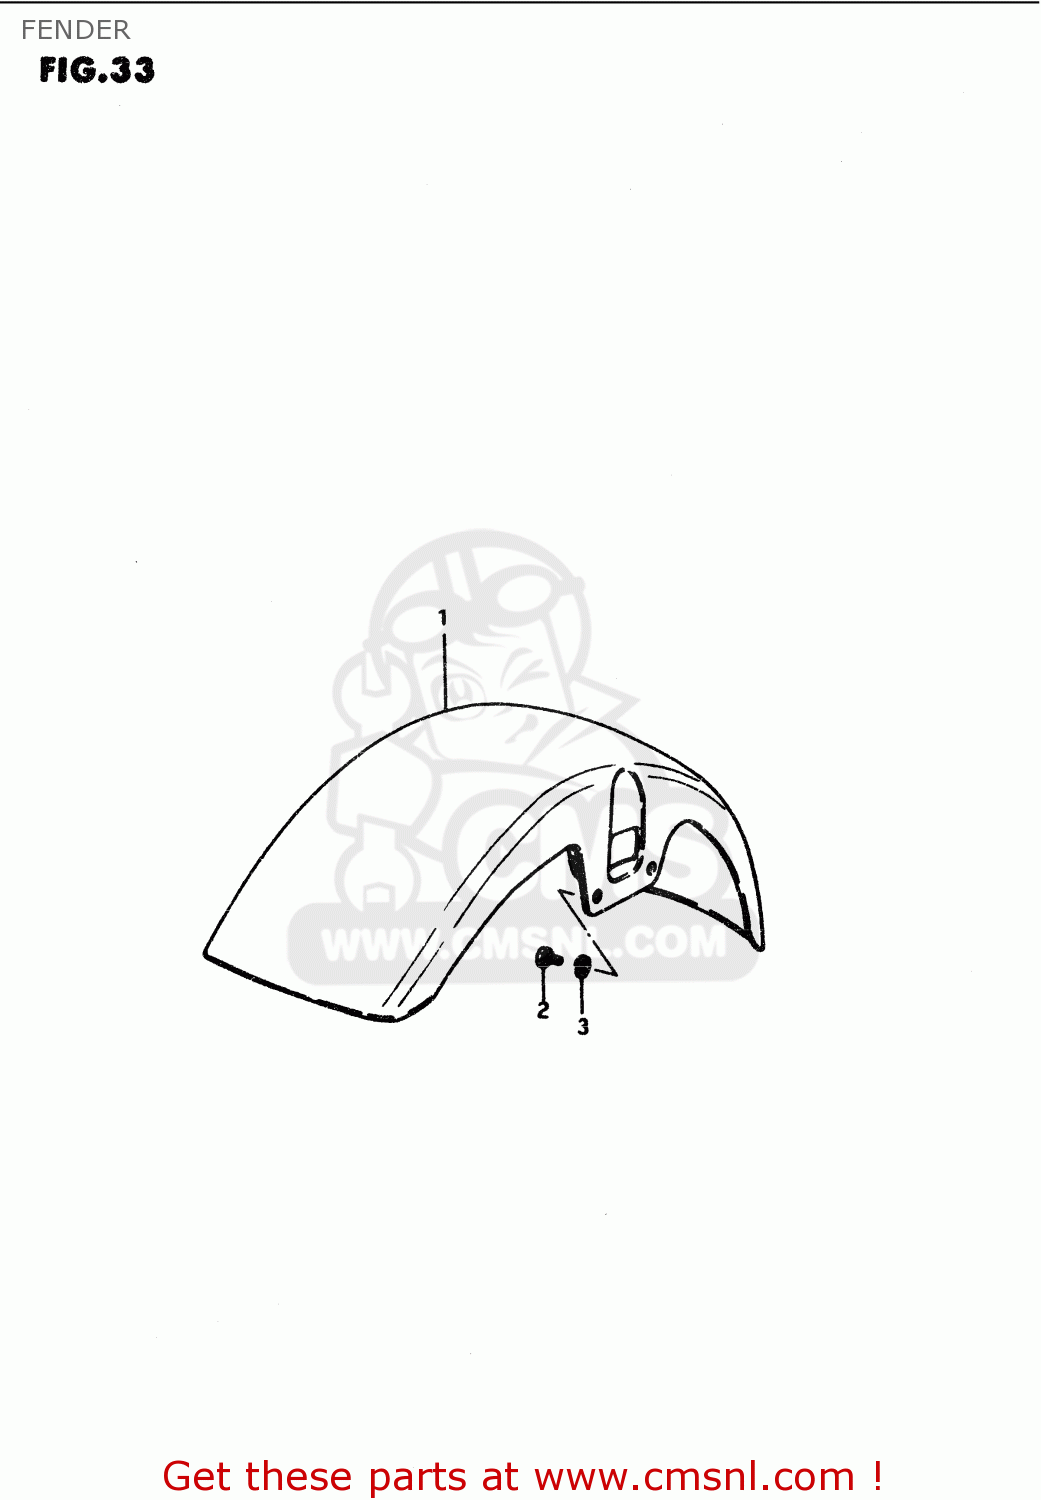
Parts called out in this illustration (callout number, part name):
1	FENDER,FR
2	BOLT
3	WASHER,LOCK
